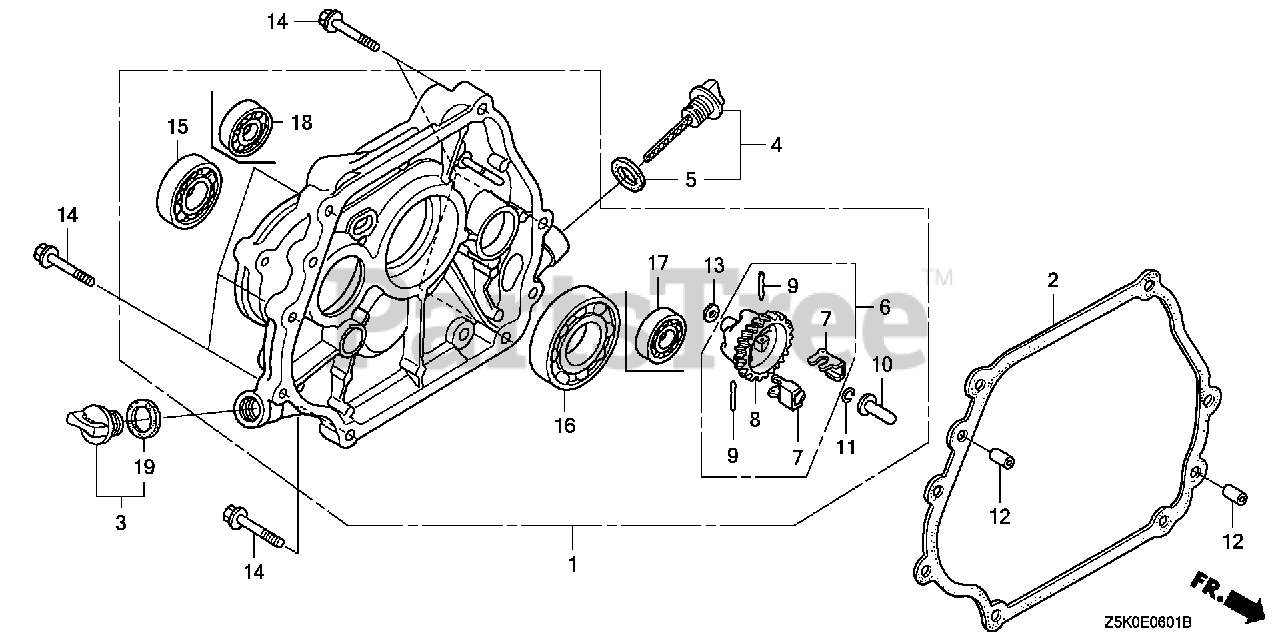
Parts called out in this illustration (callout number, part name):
1	COVER ASSY., CRANKCASE
2	GASKET, CASE COVER
3	CAP ASSY., OIL FILLER (BLACK)
4	CAP ASSY., OIL FILLER
5	GASKET, OIL FILLER CAP
6	GOVERNOR ASSY.
7	WEIGHT, GOVERNOR
8	HOLDER, GOVERNOR WEIGHT
9	PIN, GOVERNOR WEIGHT
10	SLIDER, GOVERNOR
11	CLIP, GOVERNOR HOLDER
12	PIN, DOWEL (8X12)
13	WASHER, PLAIN (6MM)
14	BOLT, FLANGE (8X35)
15	BEARING, RADIAL BALL (6204)
16	BEARING, RADIAL BALL (6206)
17	BEARING, RADIAL BALL (6202)
18	BEARING, RADIAL BALL (6302)
19	GASKET, OIL FILLER CAP
